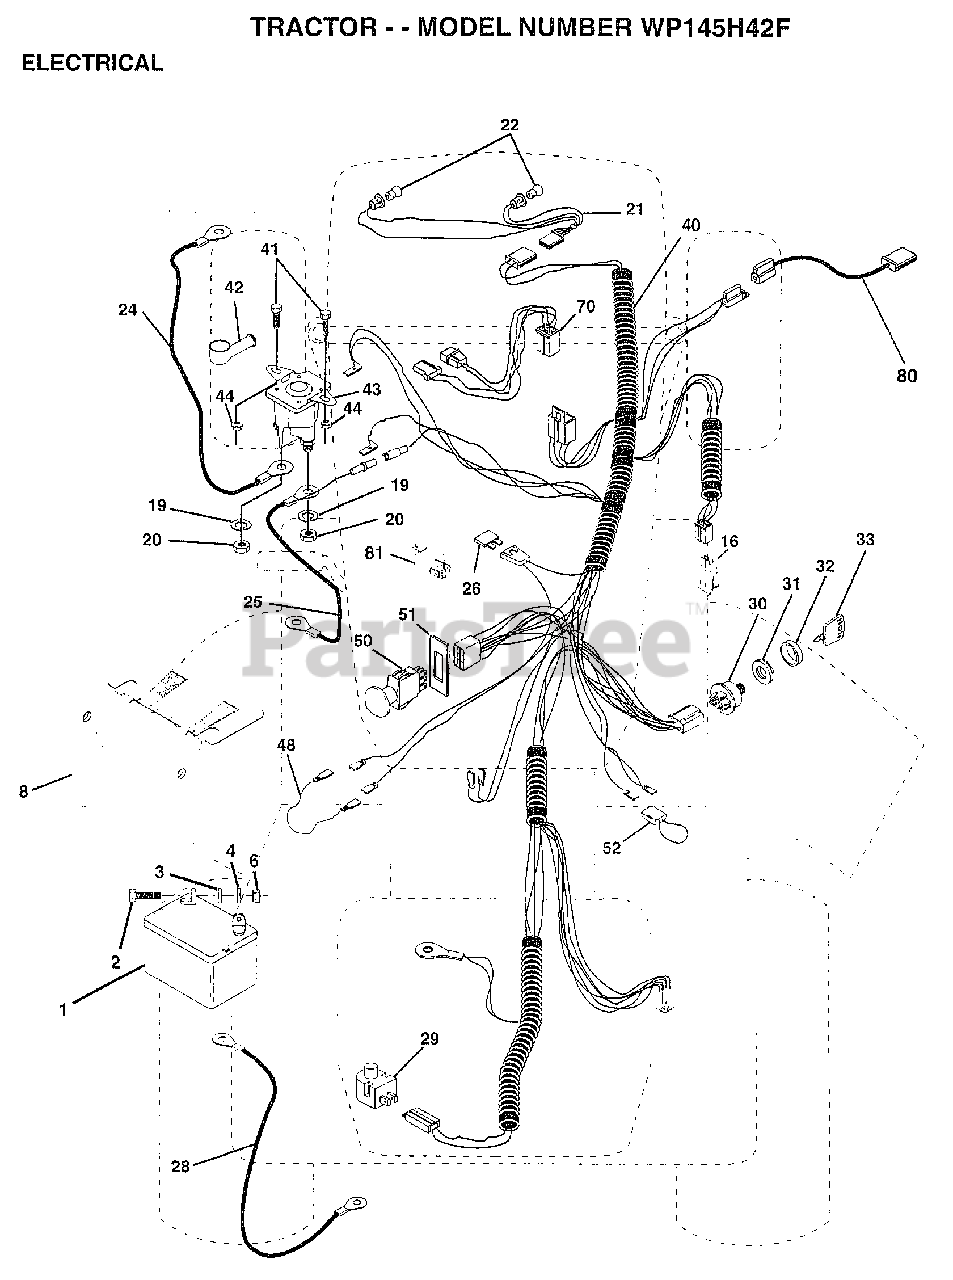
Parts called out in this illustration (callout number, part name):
3	WASHER
4	LOCKWASHER
8	"CASE,BATTERY.MECH"
16	SWITCH INTERLOCK
20	NUT
21	HARNESS.ASM.HDLIG
22	HEADLAMP BULB
24	CABLE.BTRY.6GA.RD
25	CABLE.BTRY.6GA.38
26	FUSE HYT
28	CABLE T
29	SWITCH.PLUNGER
30	SWITCH IGN 4POS
31	NUT IGNITION
32	COVER KEY SWITCH
33	KEY
40	IGNITION HARNESS
41	BOLT HXHD FIN
44	NUT HXKEP 1/4X20
48	ADAPTER AMMETER
50	PTO SWITCH.BLK
51	RING RETAIN PTO
52	PROTECTION LOOP
70	HARNESS.ENG.DUAL
80	HARNESS.CLUT.EVX.
81	RELAY ASSY T
